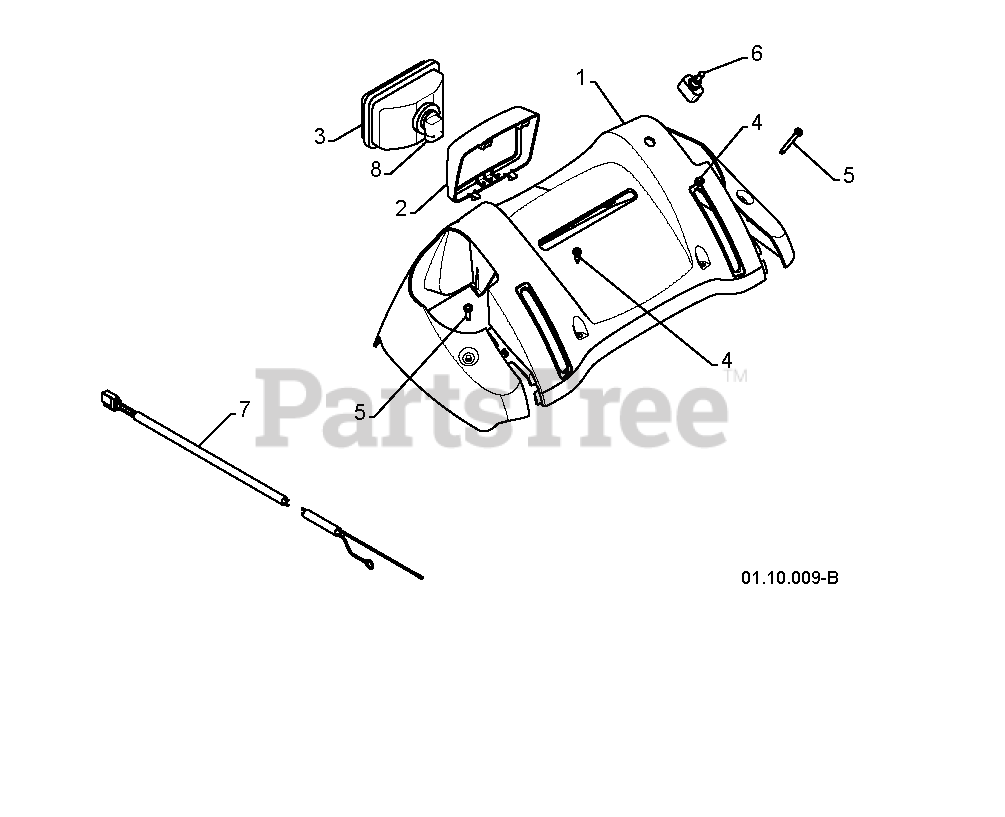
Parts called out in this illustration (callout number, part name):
1	CONSOLE, PANEL
2	BEZEL.HEADLIGHT.BLACK
3	HEADLIGHT, HALOGEN
4	SCREW, HEX HEAD, TAPPING
5	SCREW, HEX HD TAPPING #10-24 1
6	SWITCH.GRIP.HEATED
7	HARNESS.WIRE.LIGHT/GRIP.SNOW
8	BULB.HEADLIGHT.HALOGEN.
